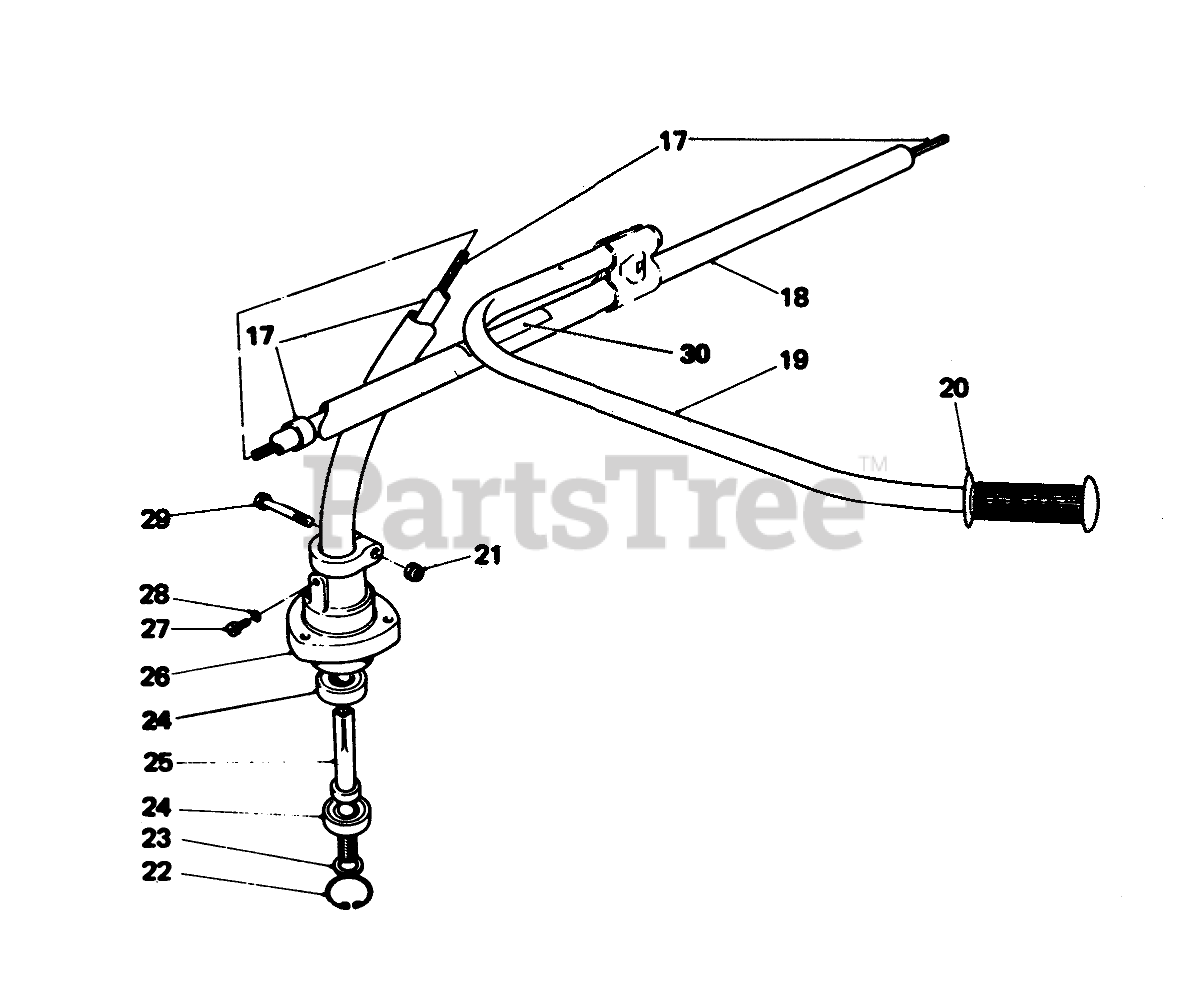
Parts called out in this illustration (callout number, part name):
17	Drive Shaft and Casing Assy.
18	Tube-Shaft Housing
19	Tube-Support Handle
20	Grip-Support Handle
21	NUT-LOCK, NI
22	RING-SNAP
23	Bearing Spacer
24	Bearing
25	POWER SHAFT
26	Bearing Case
27	Screw
28	WASHER-LOCK
29	SCREW-SHH
30	Caution Decal
